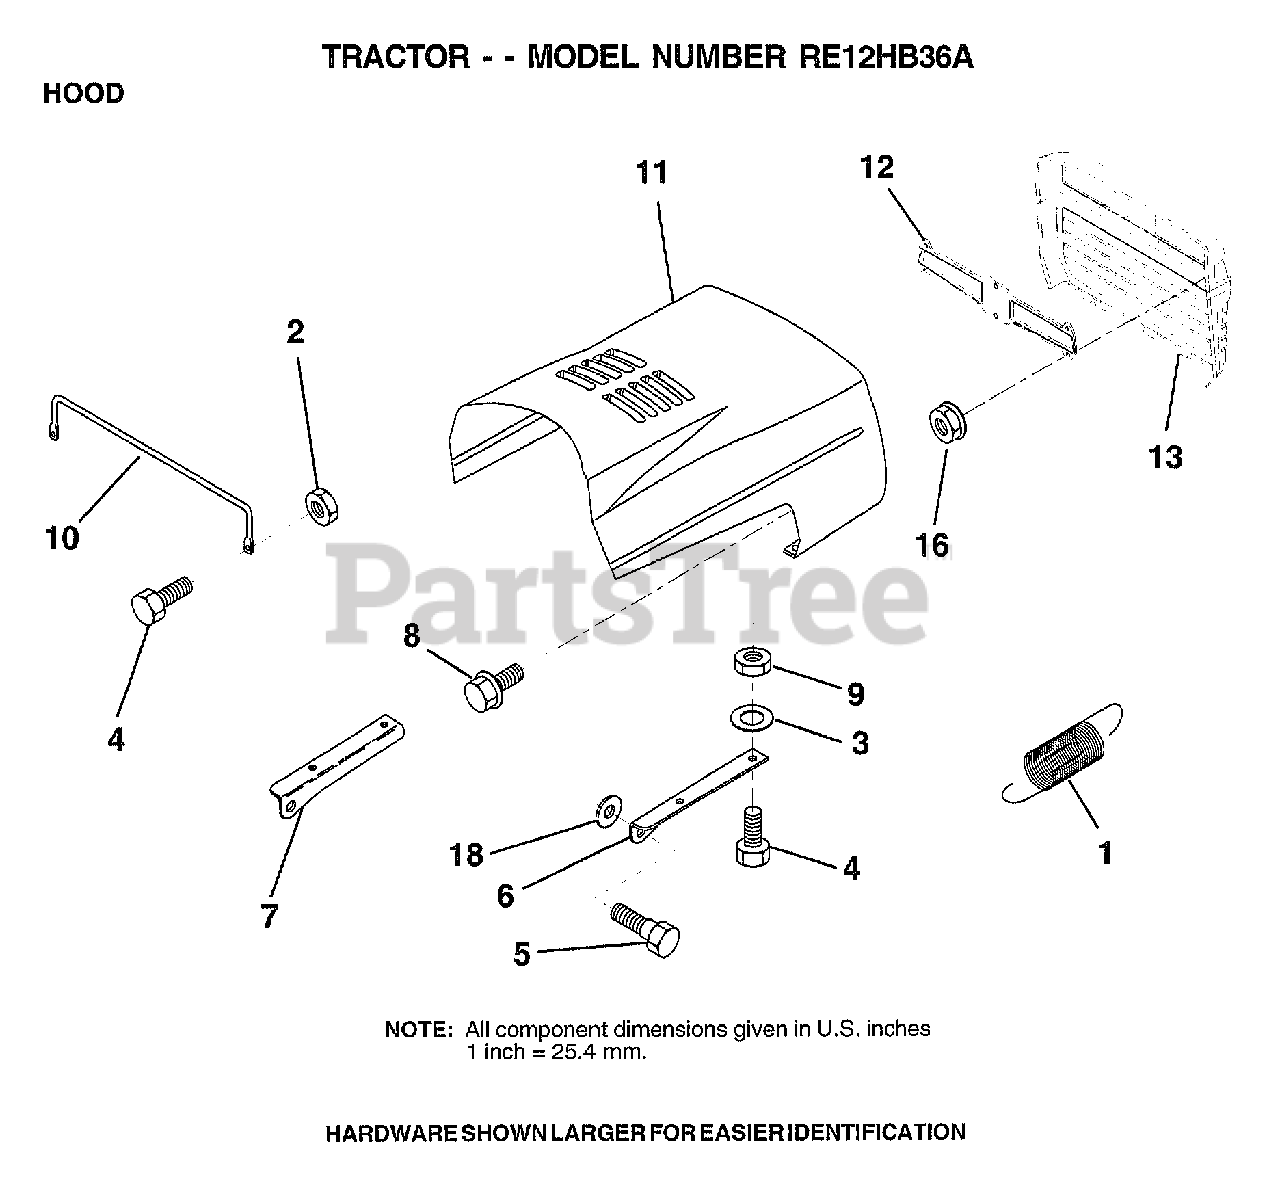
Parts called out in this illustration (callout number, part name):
1	EXT SPRING
2	NUT
3	WASHER
5	BOLT.SHLD.5/16-18
6	BRKT HOOD RH
7	BRKT HOOD LH
8	"SCREW,HWHD.HI-LO#13-16X3/4"
9	NUT
10	"BRACE,HOOD"
11	HOOD
13	GRILL (BLACK)
16	NUT
18	WASHER
